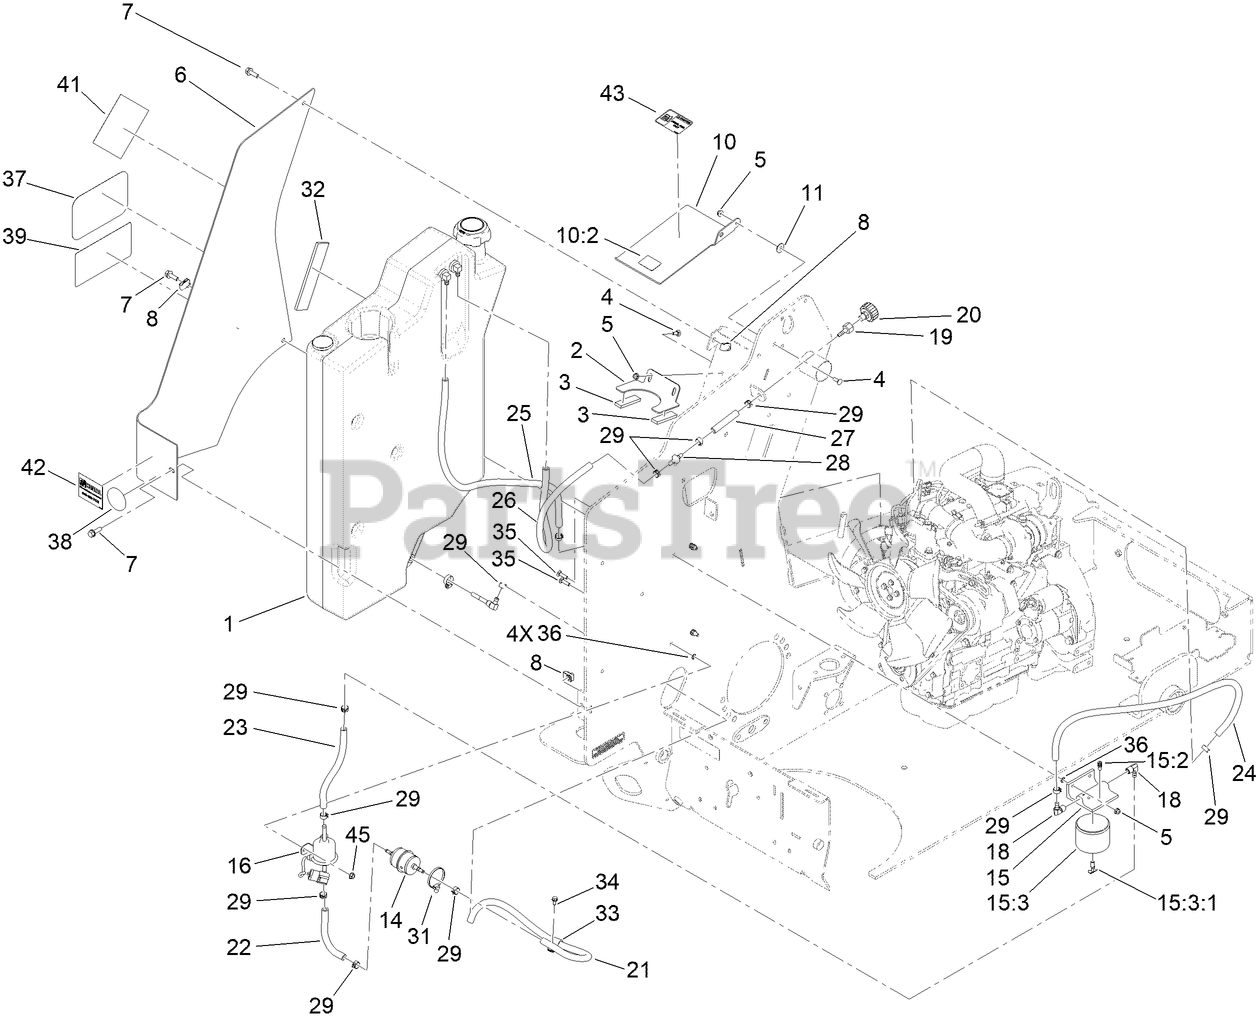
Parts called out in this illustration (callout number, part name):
1	TANK ASM-FUEL
2	BRACKET-TANK, HOLD DOWN
3	PAD-FOAM
4	BOLT-CARR
5	NUT-HF
6	TANK COVER ASM-FUEL
7	SCREW-HHF
8	NUT-CLIP, U
10	TANK BRACKET ASM-FUEL
10:2	DECAL-ULTRA LOW SULFUR DIESEL
11	WASHER-BELLEVILLE
14	FILTER-FUEL
15	FILTER HEAD ASM
15:2	VENT-AIR
15:3	ELEMENT-SPIN ON
15:3:1	VALVE-DRAIN
16	PUMP-FUEL
18	FITTING-HYD, 90
19	FITTING-STRAIGHT
20	BREATHER
21	HOSE-FUEL
22	HOSE-FUEL
23	HOSE-FUEL
24	HOSE-FUEL
25	HOSE-FUEL
26	HOSE-FUEL
27	HOSE-FUEL
28	VALVE-CHECK, FUEL
29	CLAMP-HOSE
31	CLIP-TIE
32	PAD-RUBBER
33	CLAMP-R
34	SCREW-HWH
35	SCREW-CARR
36	NUT-RETAINING
37	DECAL-TORO LOGO
38	REFLECTOR-RED
39	DECAL-TX1000 TURBO
41	DECAL-CPER0001
42	DECAL-RHSQG3X3
43	DECAL-CPER0010
45	NUT-HF
